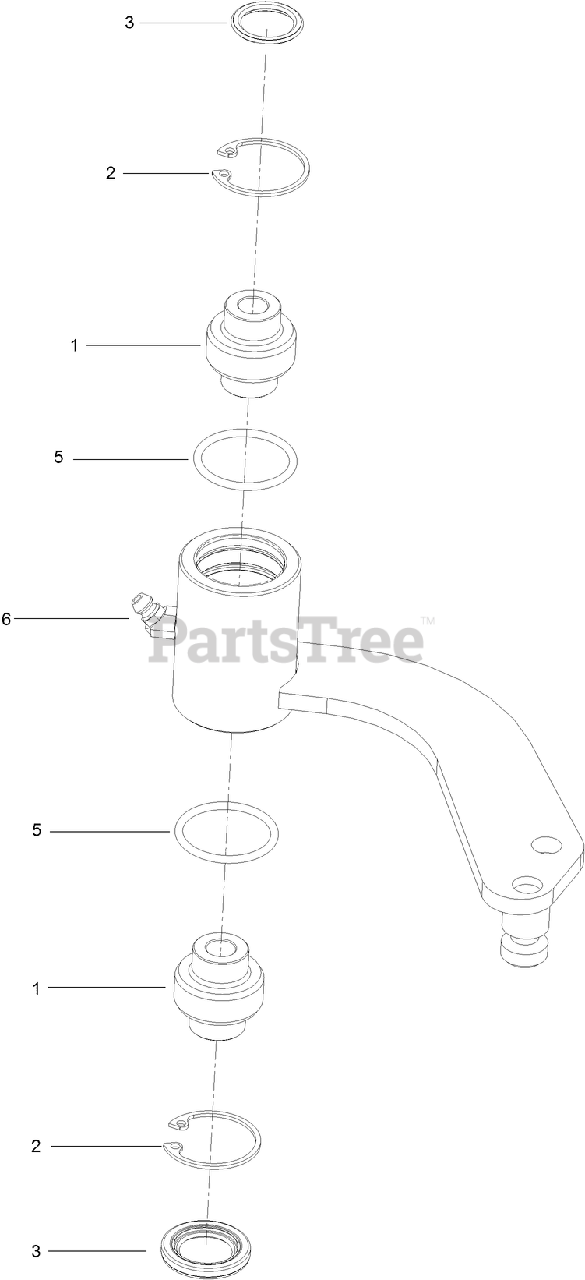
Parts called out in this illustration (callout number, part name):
1	BEARING-SPHERICAL
2	RING-SNAP
3	SEAL-LIP, SINGLE
4	O-RING
6	FITTING-LUBE, 45 DEG
